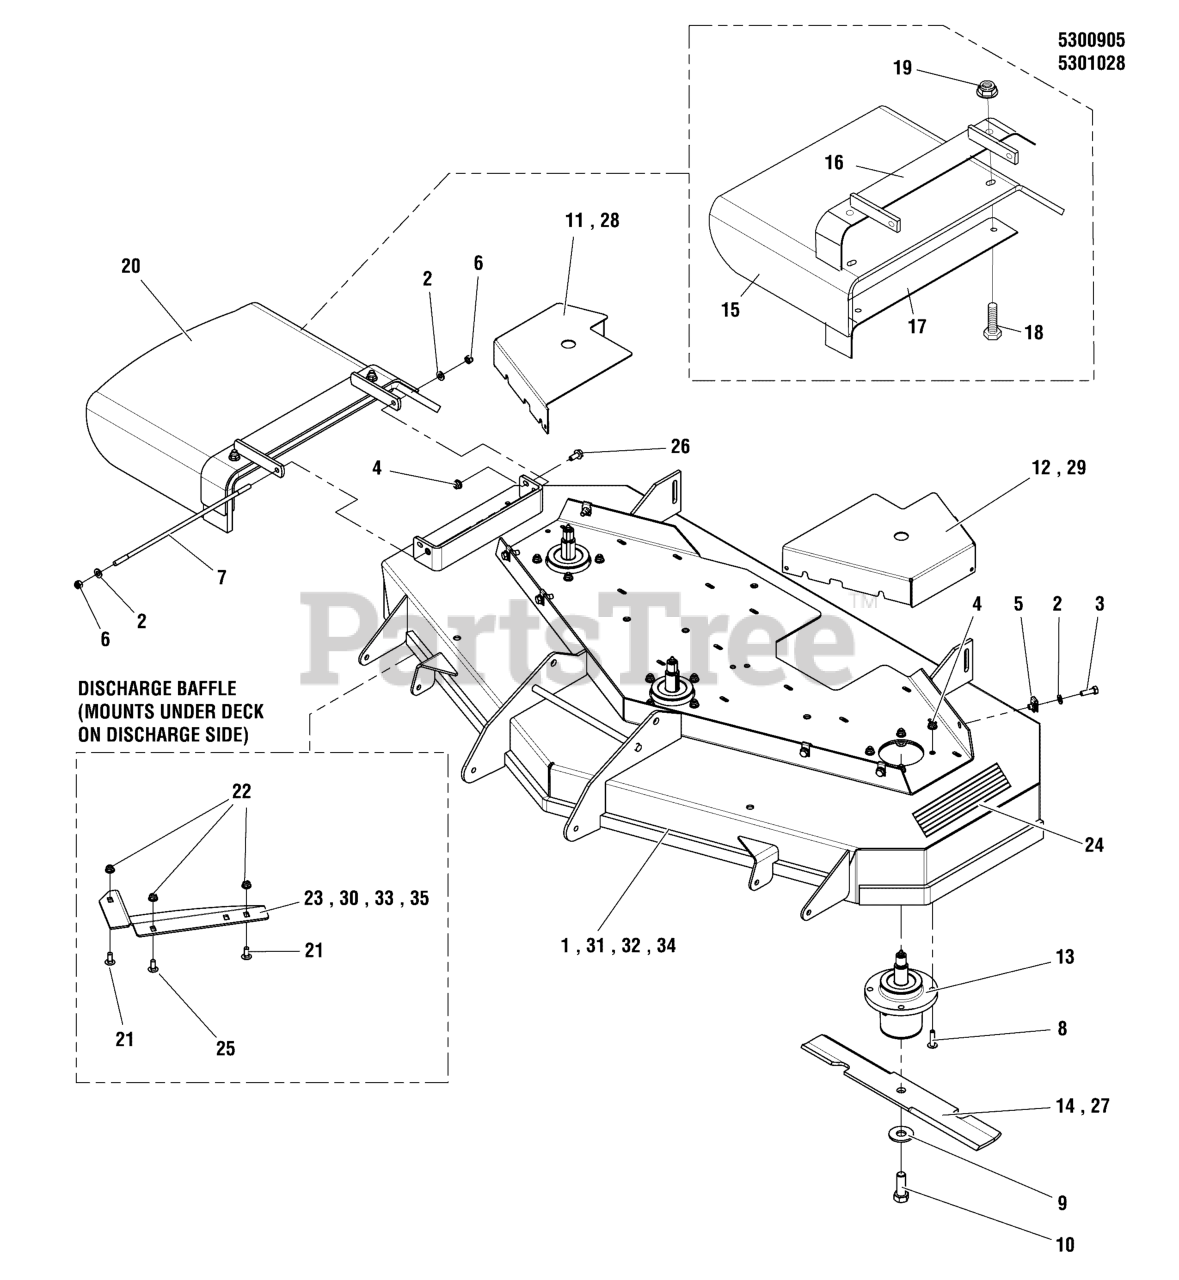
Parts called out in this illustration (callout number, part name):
1	DECK SHELL W/ DECALS, MZ1500, 52" (SV)
2	WASHER, 5/16" SAE
3	BOLT, 5/16-18 X 3/4 GD5
4	NUT, 5/16-18 HEX NYLOCK FLANGE
5	BODY CLIP, 5/16-18-7GA MATERIAL
6	NUT, 5/16-24 HEX NYLON LOCK
7	ROD, BRAKE LINKAGE
8	BOLT, 5/16-18 X 1 1/4 FLANGE
9	WASHER, 5/8 USS
10	BOLT, 5/8-11 X 1-3/4" GD8
11	GUARD, 52" DECK - RH - RED
12	GUARD, 52" DECK - LH - RED
13	ASSM, SPINDLE, LOW PROFILE
14	BLADE SET, 52" DECK
15	CHUTE, DISCHARGE, RUBBER, 44/48/52
16	WELD, MOUNT, DISCHARGE CHUTE - BLK
17	SUPPORT,DISCHARGE CHUTE - BLK
18	BOLT, 3/8-16 X 1-1/4" GD5 CZ
19	NUT, 3/8-16 HEX NYLOCK FLANGE
20	KIT, DISCHARGE CHUTE, 44/48/52
21	BOLT, 5/16-18 X 3/4", CARRIAGE
22	NUT, 5/16-18 HEX NYLOCK FLANGE
23	WELD, DISCHARGE BAFFLE, 52" - RED
24	SAFETY WALK, 4.00 X 7.50
25	BOLT, 5/16"-18 CARRIAGE, 1"
26	BOLT, 5/16-18 X 3/4 GD5
27	BLADES, SET OF THREE (3); 16.25 X.25 X 2.5, 1 X 3.5
28	GUARD, 48 DECK - RH -RED
29	GUARD, 48 DECK - LH -RED
30	WELD, DISCHARGE BAFFLE, 48" - BLK
31	DECK SHELL W/DECALS, 48 MZ1500 (5401397D)
32	DECK SHELL W/ DECALS (5403609B)
33	WELD, DISCHARGE BAFFLE, 52" - BLK
34	DECK SHELL W/ DECALS, 48 - S150X
35	PLATE, DEFLECTOR - BLK
